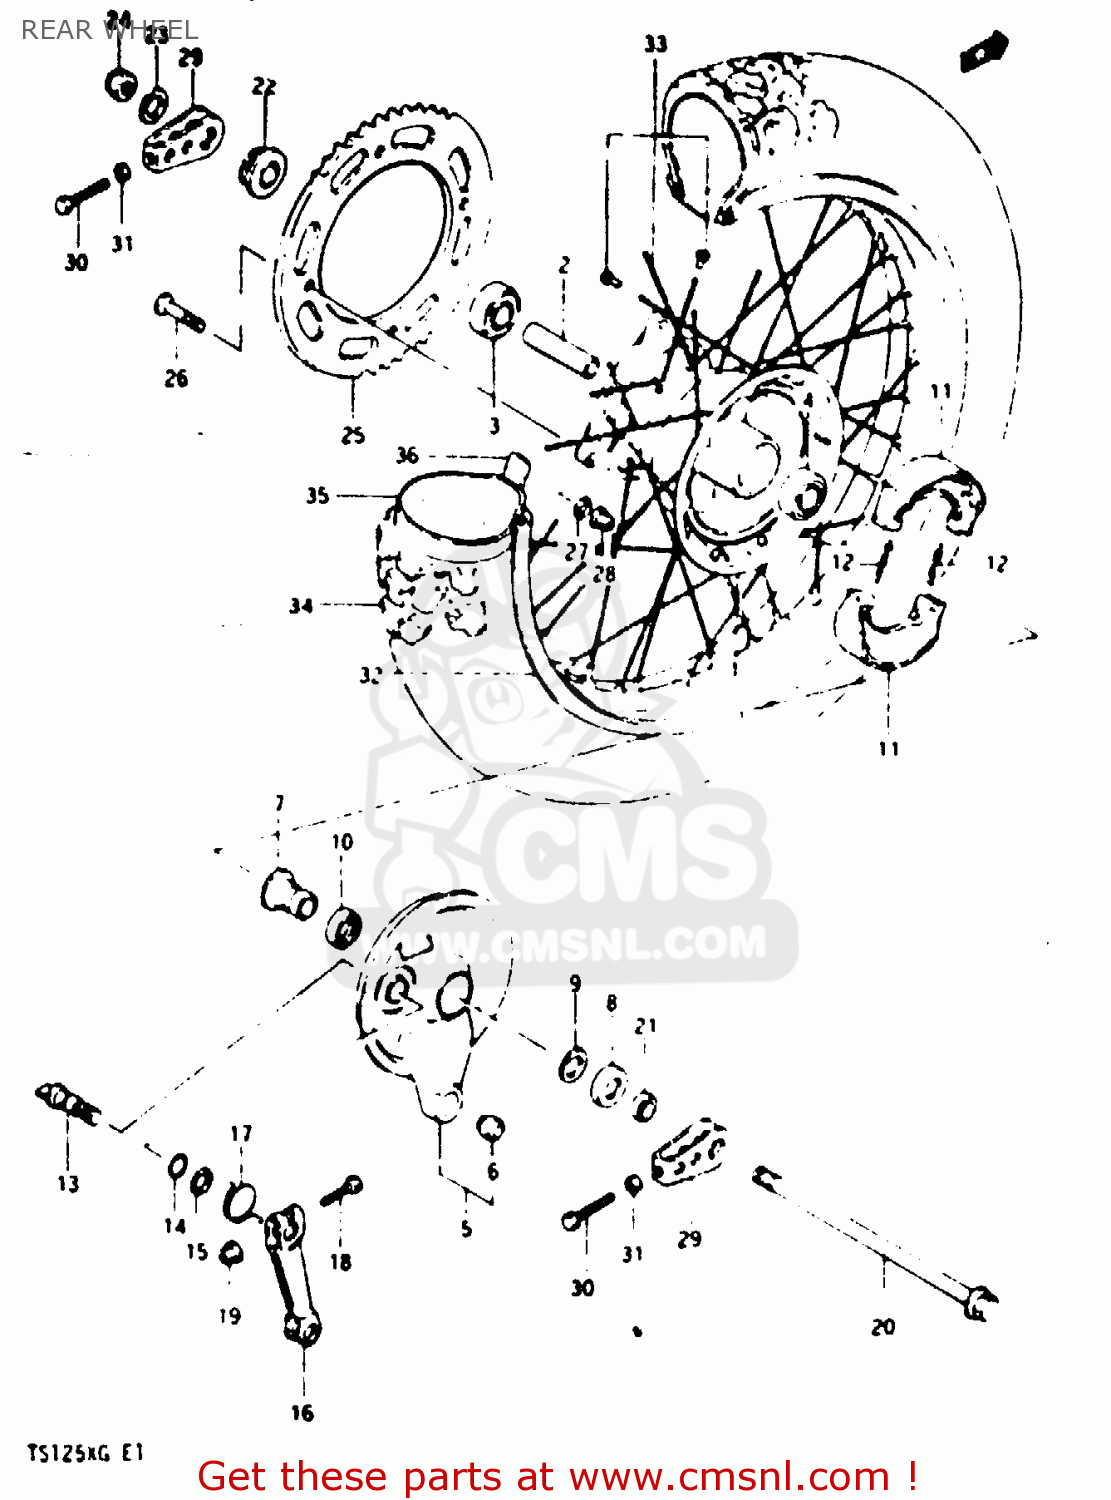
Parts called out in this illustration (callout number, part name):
1	HUB, REAR
2	SPACER(15.3X21.7X100)
3	BEARING
4	BEARING
5	PANEL SET, REAR
6	SPHERICAL BRNG,TORQUE LINK
7	SPACER,RR BRAKE ANCHOR PANEL
8	CVR,RR BRAKE AHR PNL DUST SEAL
9	WASHER,THRUST
10	SEAL,OIL(20X27X5)
11	SHOE, BRAKE
12	SPRING
13	CAM, BRAKE
14	O-RING (D:2.4 ID:13.8)
15	WASHER (14.5X22X1.6)
16	LEVER,RR BRAKE CAM
17	SPRING
18	BOLT 6X35
19	NUT
20	AXLE,RR
21	SPACER, RH
22	SPACER,RR AXLE,L
23	WASHER
24	NUT
25	SPROCKET,RR
26	SCREW(8X33.5)
27	WASHER
28	NUT
29	ADJUSTER,CHAIN
30	BOLT
31	NUT
32	RIM, WHEEL (2.15*18)
33	SPOKE SET, REAR
34	TIRE, REAR (110/80-18) BS
35	TUBE ASSEMBLY,WHEEL,INNER
36	PROTECTOR,WHEEL,INNER
